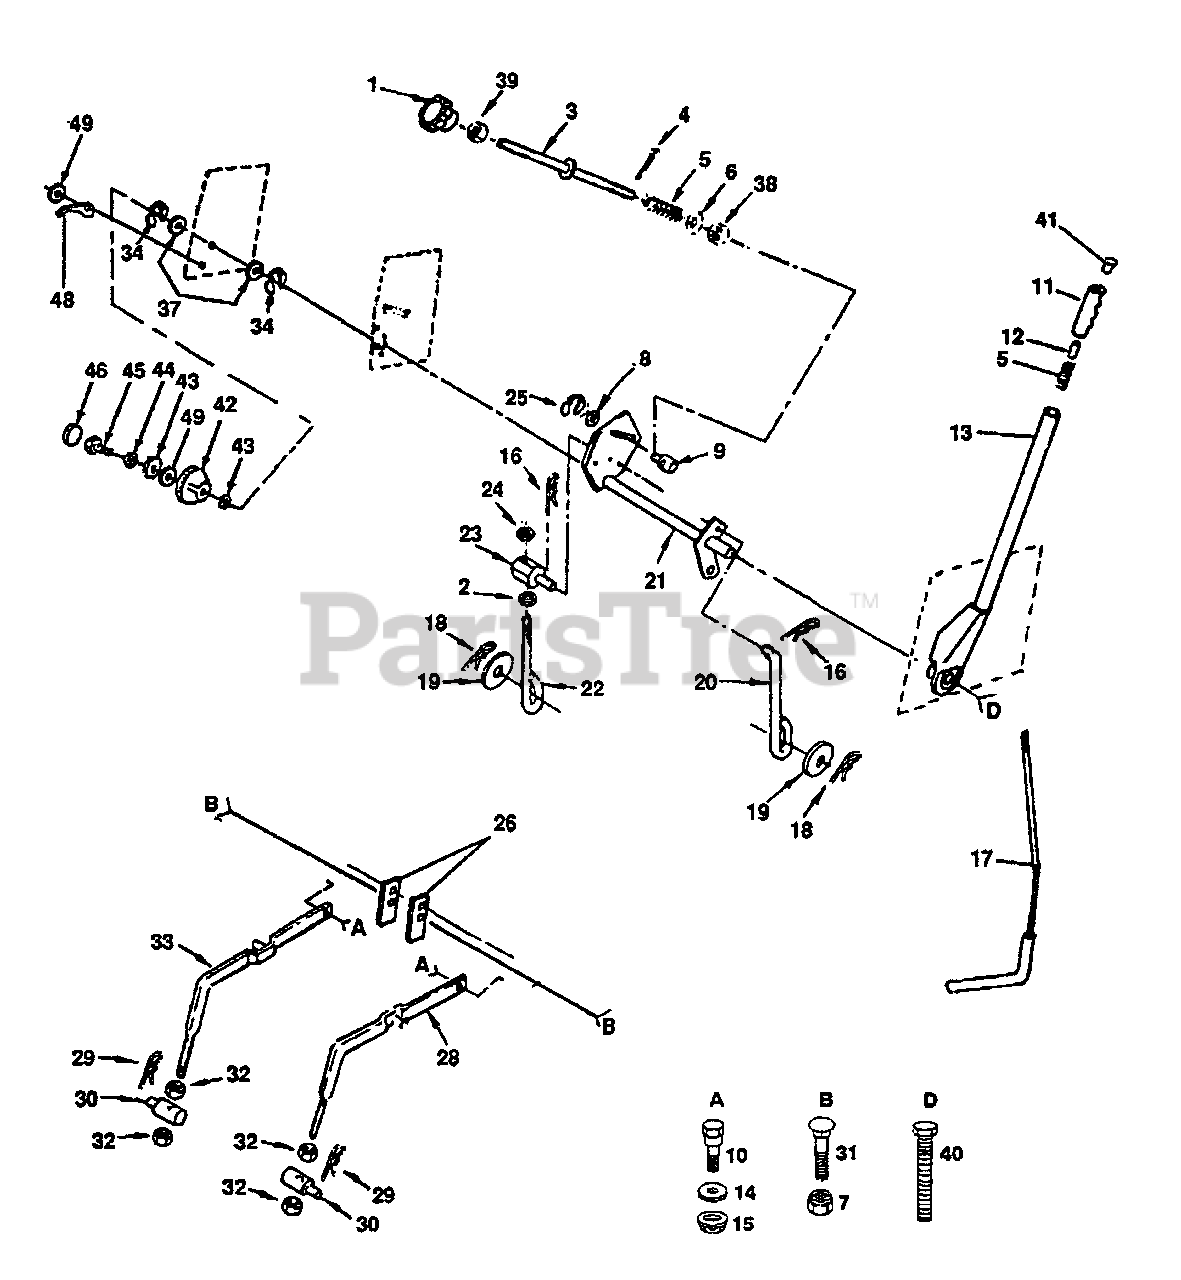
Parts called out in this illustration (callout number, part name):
1	Handle, Lift, Adjustment
2	Nut, Hex 3/8-16
3	Rod, Adjust, Lift
4	Pin, Cotter 3/32 x 1/2
5	Spring
6	Washer 13/32 x 5/8 x 16 Gauge
7	Nut, Crowniock 3/8-16
8	Washer 15/32 x 3/4 x 16 Gauge
9	Trunnion, Depth Stop
10	Bolt, Shoulder 3/8-16
11	Grip, Handle
12	Plunger, Lever, Lift
13	Lever, Lift
14	Spring, Washer
15	Nut Center, Lock, Flange 3/8 x 16
16	Retainer, Spring
17	Rod, Lever
18	Retainer, Spring
19	Washer 17/32 x 15/16 x 16 Gauge
20	Link, Lift
21	Shaft, Lift, Assembly
22	Link, Lift, Adjust
23	Trunnion, Lift
24	Locknut 7/16-14
25	Ring, Klip
26	Upstop, Mower
28	Arm, Suspension, R.H.
29	Retainer, Spring
30	Trunnion, Lift, Lower
31	Bolt, Carriage 3/8-16 UNC x 1
32	Nut, Hex, Fin. 1/2-13
33	Arm, Suspension, L.H.
34	E-Ring, Truarc
37	Washer 29/32 x 1-1/4 x 18 Gauge
38	Nut, Special
39	Nut, Hex, Jam 3/8 x 16 UNC
40	Bolt, Hex 3/8-16 x 1-1/2
41	Button, Plunger
42	Scale, Height, Indicator
43	Washer 11/32 x 1-1/2 x 10 Gauge
44	Washer, Lock, Heavy, Helical, Spring
45	Bolt, Hex, Fin. 5/16-18 UNC x 1
46	Plug, Hole
48	Pointer, Height Indicator
49	Washer, Nylon
